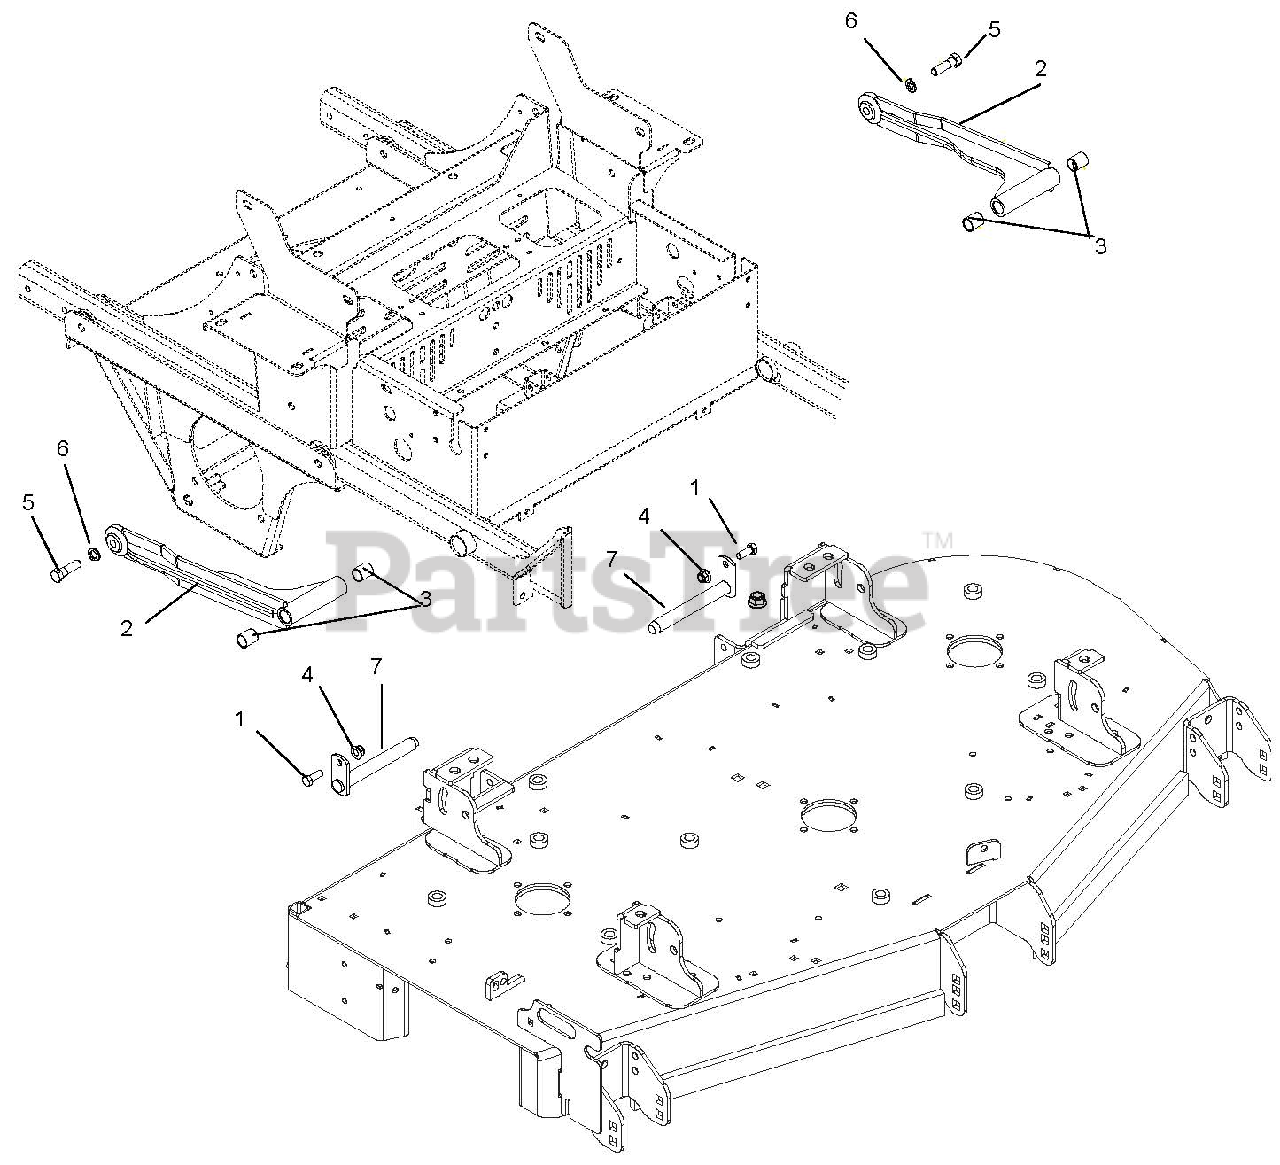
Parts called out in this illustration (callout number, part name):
1	BLT-HEX .38-16X1.00 GR5 YWZC
2	ASSEMBLY, 200I DECK PUSHER ARM
3	BRG, .750 X .875 X 1.000
4	NUT-LK-NYL-FLG .38-16 YWZC
5	BLT-HEX .50-13X1.75 GR5EP80 YZ
6	WSHR-LK .50X.125 REG YWZC
7	WELDMENT, MOWER MTG. PIN
